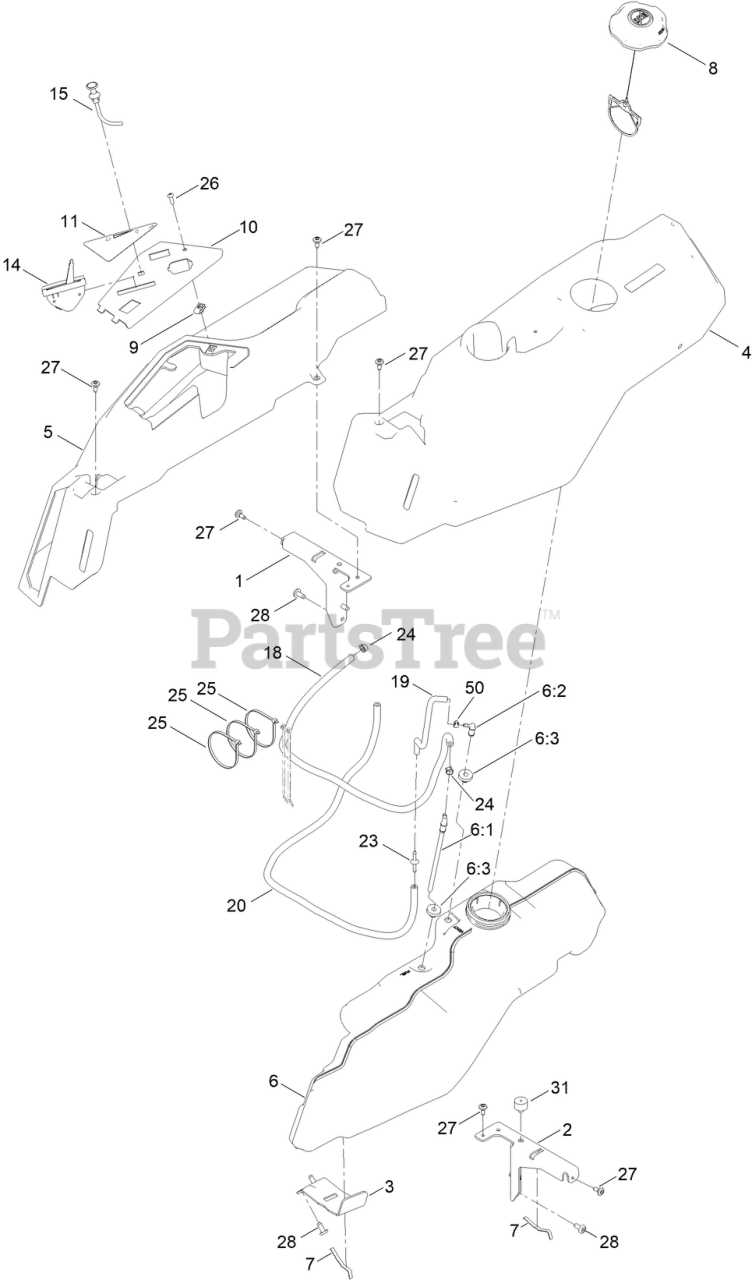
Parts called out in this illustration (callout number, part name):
1	SUPPORT-POD, RH
2	SUPPORT-POD, LH
3	SUPPORT-TANK, FUEL
4	POD-LH
5	POD-RH
6	TANK-FUEL ASM
6:1	CONNECTOR-ELBOW, 90 DEG
6:2	FITTING-ELBOW 90
6:3	BUSHING
7	SPRING
8	CAP-FUEL, RATCHETING
10	PANEL - CONTROL
11	DECAL-PANEL, CONTROL
14	CABLE-THROTTLE
15	CABLE-CHOKE
18	HOSE-FUEL
19	HOSE-FUEL
23	ADAPTER ORIFICE
24	CLAMP-HOSE
25	TIE-CABLE
26	SCREW-PRH
27	SCREW-SHOULDER
31	BUMPER-GROMMET
50	CLAMP-HOSE
